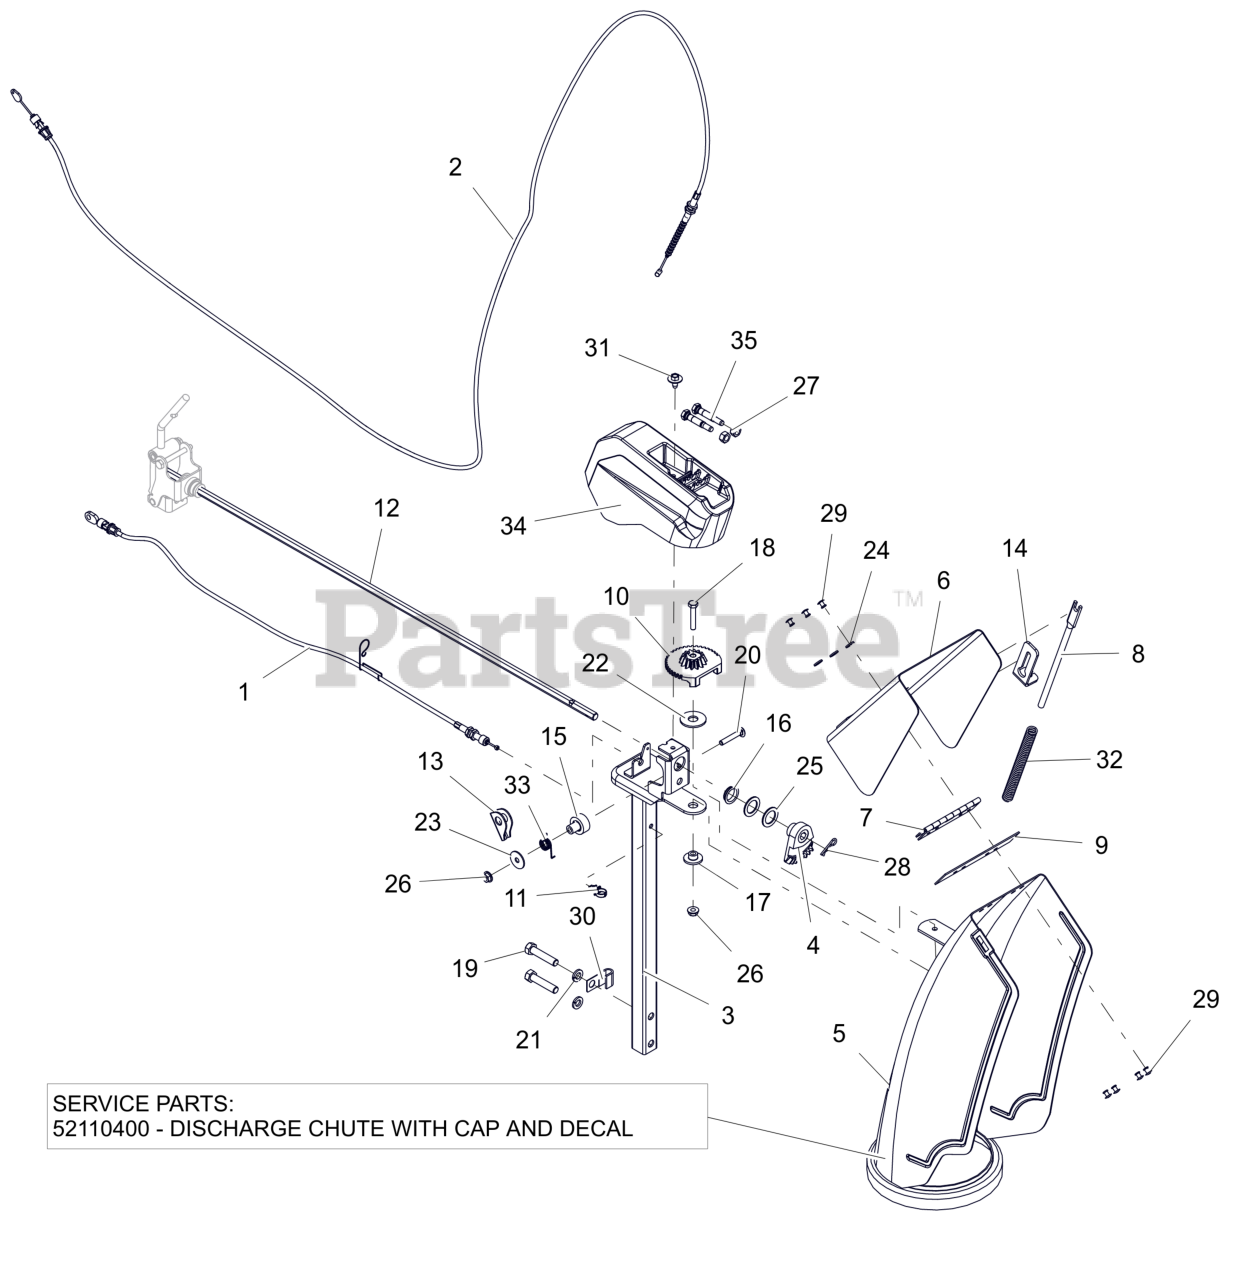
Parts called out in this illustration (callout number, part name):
1	CABLE, CHUTE LOCK, PRO
2	CABLE, DEFLECTOR - DELUXE
3	PEDESTAL, CHUTE -QUICK STICK
4	GEAR, CHUTE-ACTUATION
5	CHUTE,DISCHARGE,NOTCHED,QT
5	CHUTE, DISCHARGE W/CAP
6	CAP, LARGE REMOTE W/DECAL
8	ROD, DEFLECTOR CAP
9	CAP SEAL 5.50
10	GEAR, CHUTE
11	CLIP, CABLE GUIDE
12	ROD, HEX - CHUTE ROTATION
13	ARM, LOCKING
14	BRKT, ANCHOR - CABLE
15	BUSHING, LOCK ARM
16	BUSHING, POLYLINER-.75 SNAPIN
17	BSHG-FLG .265X.477X.375X1.00
18	BLT, HEX .25-20X1.50 G5 ZCC
19	BLT, HEX .38-16X1.75 G5 ZCC
20	BLT, RHSN .25-20X1.50 G5 ZCC
21	WSHR,LK-REG .375X.094 ZCC
22	WSHR-FLT-NYL .515X1.375X.093
23	WSHR,FLT .281X1.000X.063 ZCC
24	WSHR,FLT .196X.500X.066 ZCC
25	WSHR, FLT .754X1.125X.062 ZCC
26	NUT-LK-CTR-FLG .25-20 ZC120
27	NUT,LK-CTR .31-18 GA ZCC
28	PIN, HAIR #213 .08X1.19 ZCC
29	RVT, POP .1875 ZCC
30	J-CLAMP
31	SCR, TAP .25-20X.50 LG HWH ZCC
32	SG-COMP .08X.40X6.50 14#/IN
33	SG-TORS
34	COVER- QUICK TURN MOUNT
35	SHEAR BOLT SERVICE ASSEMBLY (INCLUDES NUT)
